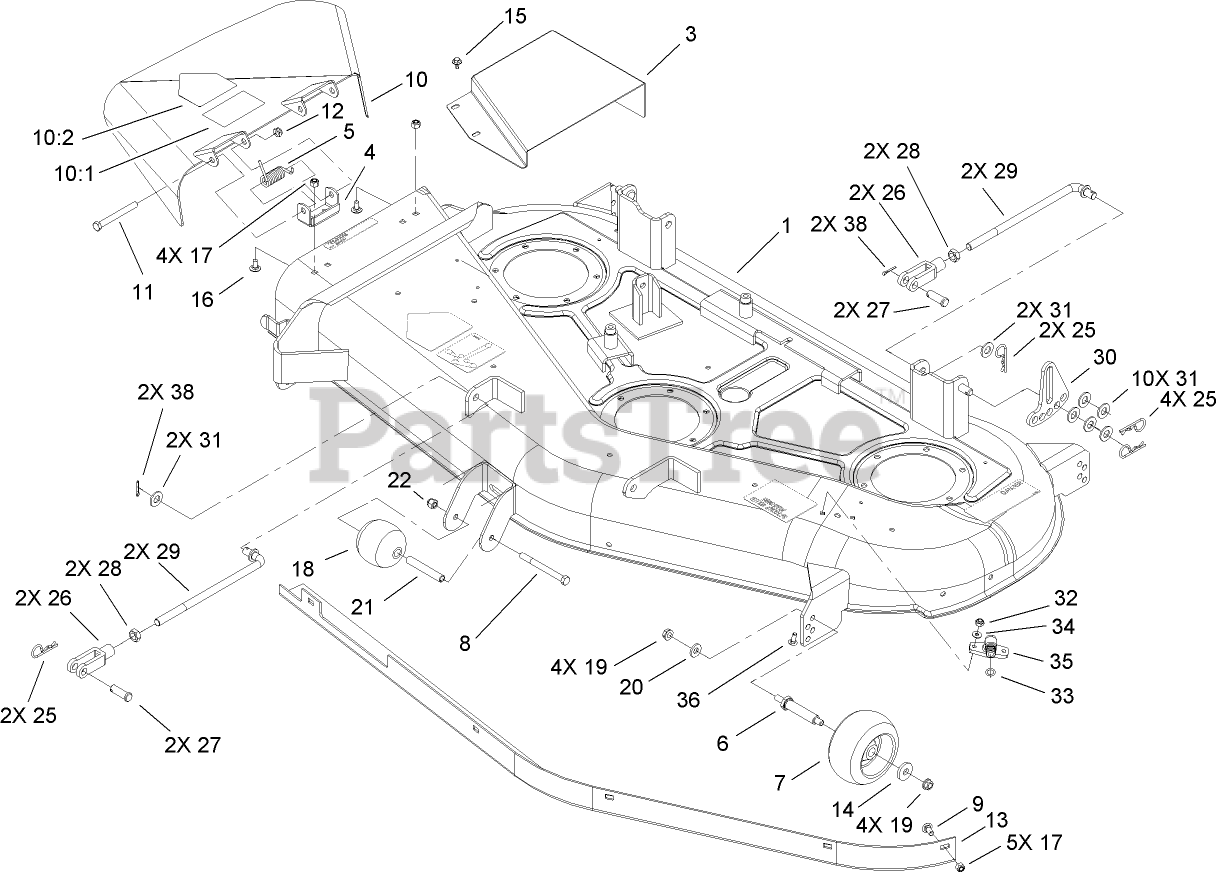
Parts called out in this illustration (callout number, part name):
3	COVER-BELT, RH
4	BRACKET-PIVOT
5	SPRING
7	ROLLER-SCALP, ANTI
8	SCREW-HH
9	SCREW-CARR
10:1	DECAL-DANGER
10:2	DECAL-DANGER
11	SCREW-HH
12	NUT-HEX
14	WASHER
15	SCREW-HHFTF
16	SCREW-CARR
17	NUT-LOCK, NI
18	ROLLER
19	NUT-HHF, WHIZ
20	WASHER-BELLEVILLE
21	TUBE-SPACER, WHEEL
22	NUT-LOCK, NI
25	PIN-COTTER
26	CLEVIS
27	PIN-CLEVIS
28	NUT-JAM
30	LINK-HOC, ADJUSTING
31	WASHER-FLAT
32	NUT-LOCK, NI
33	O-RING
34	WASHER-FLAT
36	BOLT-CARR
38	PIN-COTTER
